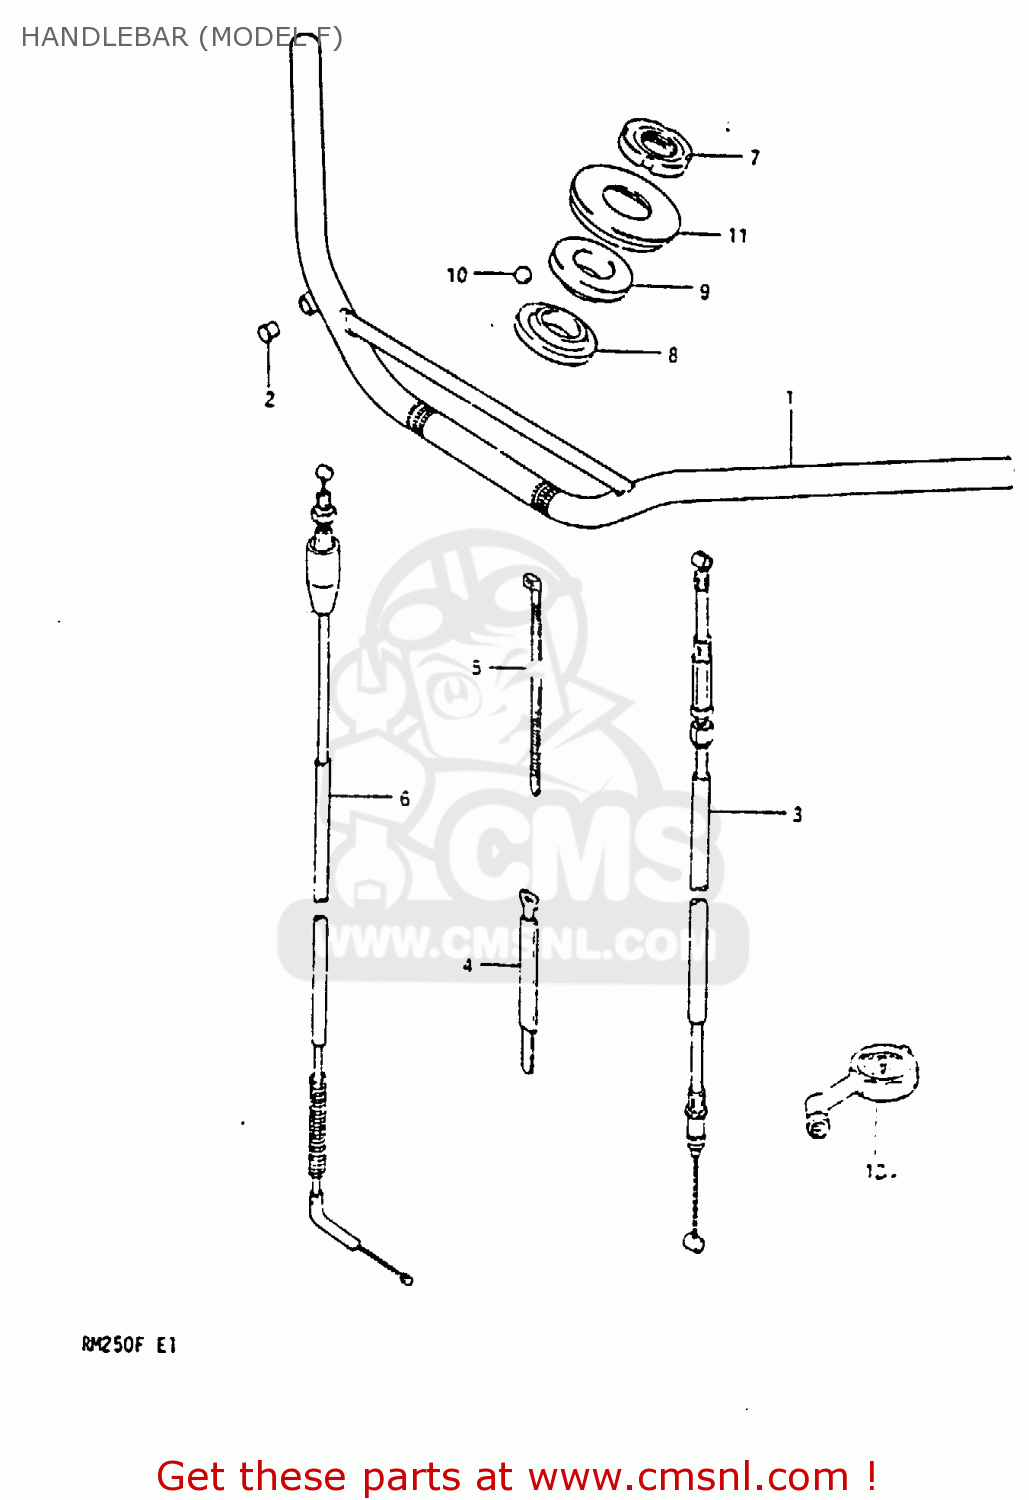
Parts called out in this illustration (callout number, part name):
1	HANDLEBAR
2	CAP(OD:14)
3	CABLE ASSY,CLUTCH
4	CLAMP
5	CLAMP(L:235)
6	CABLE ASSEMBLY,THROTTLE
7	NUT,STEERING STEM
8	RACE,STEERING,INNER,UPPER
9	RACE,STEERING,OUTER,UPPER
10	BALL
11	SEAL,STEERING UPR DUST
12	GAUGE ASSY,AIR PRESSURE
